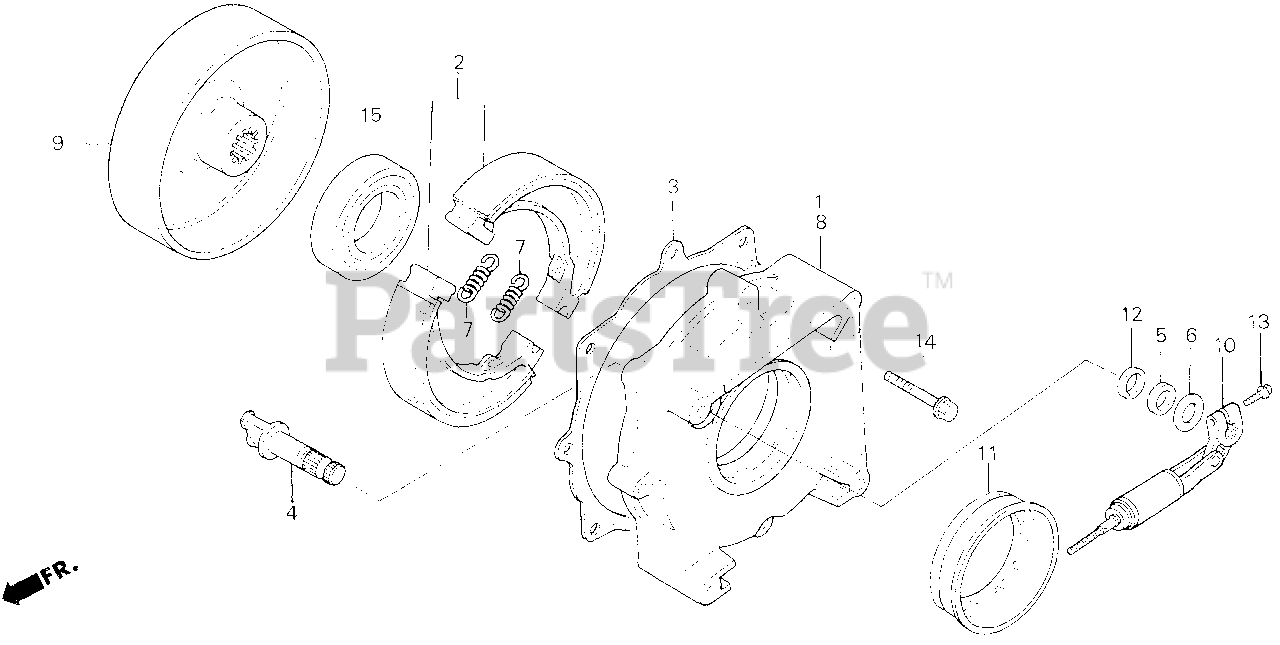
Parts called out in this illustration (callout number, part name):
1	PANEL, R. BRAKE
2	SHOE KIT, BRAKE
3	GASKET, BRAKE PANEL
4	CAM, BRAKE
5	DUST SEAL, BRAKE CAM
6	WASHER, BRAKE CAM
7	SPRING, BRAKE SHOE
8	PANEL, L. BRAKE
9	DRUM, BRAKE
10	ARM, BRAKE
11	DUST SEAL (37X58X9)
12	DUST SEAL (17X23X3) (NOK)
13	BOLT, FLANGE (8X25)
14	BOLT, FLANGE (8X40)
15	BEARING, RADIAL BALL (6007)
